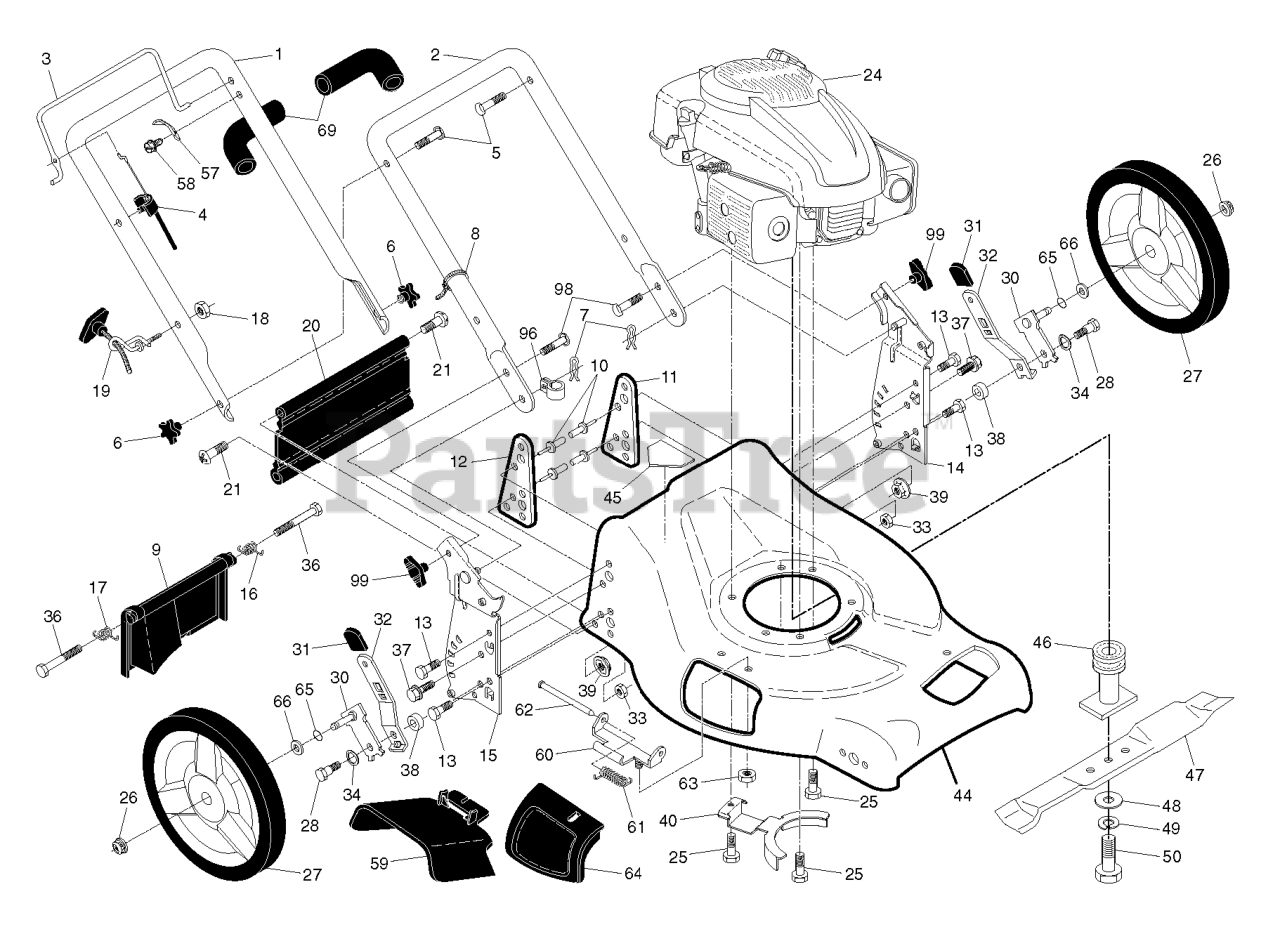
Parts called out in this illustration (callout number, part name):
1	HANDLE.ASM.GRY.W/GRIP
2	HANDLE.LOWER.D-STRAIT.GREY
3	BAIL.DSTRT.AW.CREAS.ORAN
4	RP CABLE.MZR.54.10.SNAP.IN.RT
5	BOLT, HANDLE 5/16-18X1.75
6	KNOB.HANDLE.PLASTIC.STAR.BLACK
7	HAIRPIN COTTER
8	TIE GUIDE
9	REAR DOOR ASSEMBLY
10	RIVET BLIND
11	SUPPORT BRACKET LH
12	BRACKET.SUPRT.RH.21.FWGD
13	SCREW 14-20 X 5/8
14	BRACKET.ASM.HDL.LT.21FGD.HW.OR
15	BRACKET.ASM.HNDL.RT.21.FGD.HW
16	SPRING.REAR.DOOR.EZ.21.LT
17	SPRING.REAR.DOOR.EZ.21.RT
18	NUT
19	RB GUIDE.ROPE.STD.BLK.ZIN WSL
20	SKIRT.REAR.21 FWGD.BLACK
21	HINGE SCREW
25	BOLT 3/8-16X1-1/8
26	NUT.HEX.FLANGE.3/8-16.LOCKNUT
27	WHEEL ASSY
28	SHOULDER BOLT 5/16-18
30	ARM.ASM.AXLE.REAR.5/9.POS.BZP
31	SELECTOR KNOB
32	SELECTOR SPRING
33	NUT.FLANGE.5/16
34	WASHER.CURVED.CYLINDRICAL
37	BOLT.FIN.HEX.5/16-18X3/4
38	SPACER.HEIGHT.ADJUSTER
39	NUT.71038.31-18.HEX.NYLOCK
40	BRACKET.KEEPER.BELT
44	HOUSING.21.FWD.ORANGE.WALK
45	DANGER DECAL
46	RP ADAPTER.BLADE.25MM.21F
47	BLADE.21.PUSH/RWGD/FWGD
48	WASHER,HARDEN
49	LOCKWASHER
50	SCREW, HEX HD 3/8-24 X 1-3/8
57	BRACKET UPSTOP
59	DEFLECTOR.CLIPPIN.21.FGD
60	BRACKET.ASM.HINGE.21.FWGD.
61	SPRING.TORSION
62	ROD.HINGE.21
63	LOCKNUT.NYLOC.1/4-20
64	DOOR.MULCH.21.REAR.FWGD
65	O-RING..070X.487.NEOPRENE
66	WASHER.FLAT.1/2
69	GRIP.HANDLE.FOAM.WIDE.(1 SIDE)
96	CLIP.CABLE.BLK
98	BOLT
99	KNOB, DEFLECTOR
